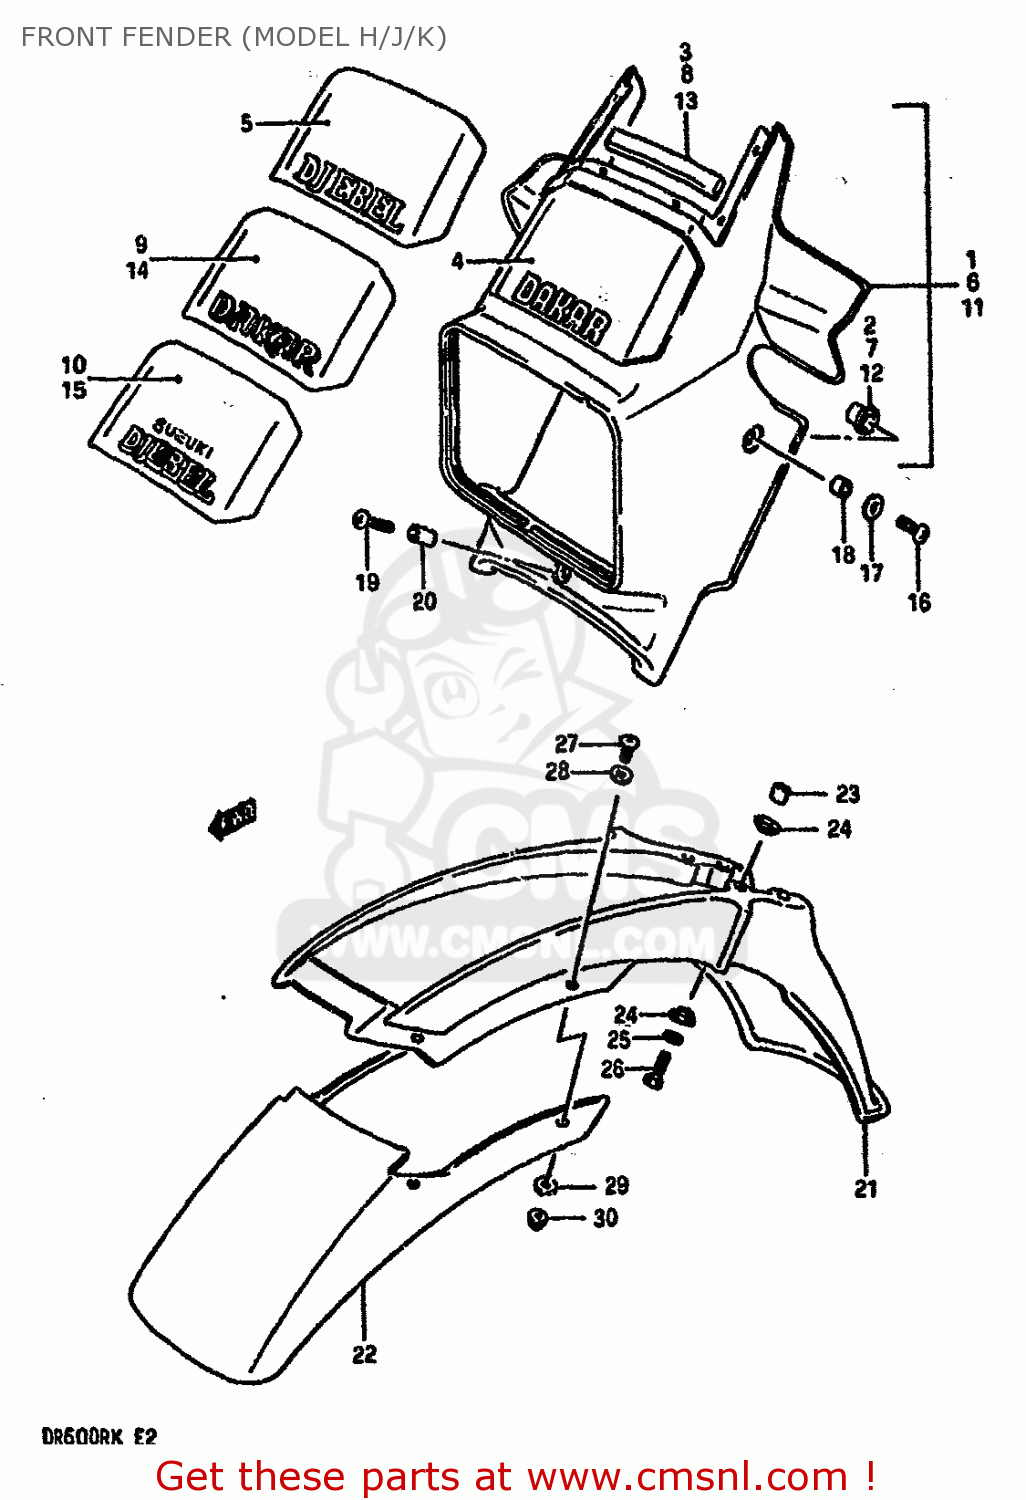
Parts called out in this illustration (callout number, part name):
1	COVER,HEADLAMP (WHITE)
2	BUSH, SIDE (WHITE)
3	CUSHION,HEADLAMP COVER
4	TAPE, HEADLAMP COVER
5	TAPE,HEADLAMP COVER
6	COVER,HEADLAMP (WHITE)
7	BUSH, SIDE (WHITE)
8	CUSHION,HEADLAMP COVER
9	TAPE,HEADLAMP COVER
10	TAPE,HEADLAMP COVER
11	COVER,HEADLAMP (WHITE)
12	BUSHING,HEADLAMP COVER,SIDE
13	CUSHION,HEADLAMP COVER
14	TAPE,HEADLAMP COVER
15	TAPE,HEADLAMP COVER
16	SCREW
17	WASHER
18	SPACER
19	SCREW, LOWER
20	SPACER (6.1X9X31.5)
21	FENDER, FRONT REAR (WHITE)
22	FENDER, FRONT (BLUE)
23	SPACER(6.1X9X7.5)
24	WASHER
25	WASHER,LOCK
26	BOLT
27	SCREW
28	WASHER (6.5X18X1.6)
29	WASHER (6.7X16X1.8)
30	NUT
